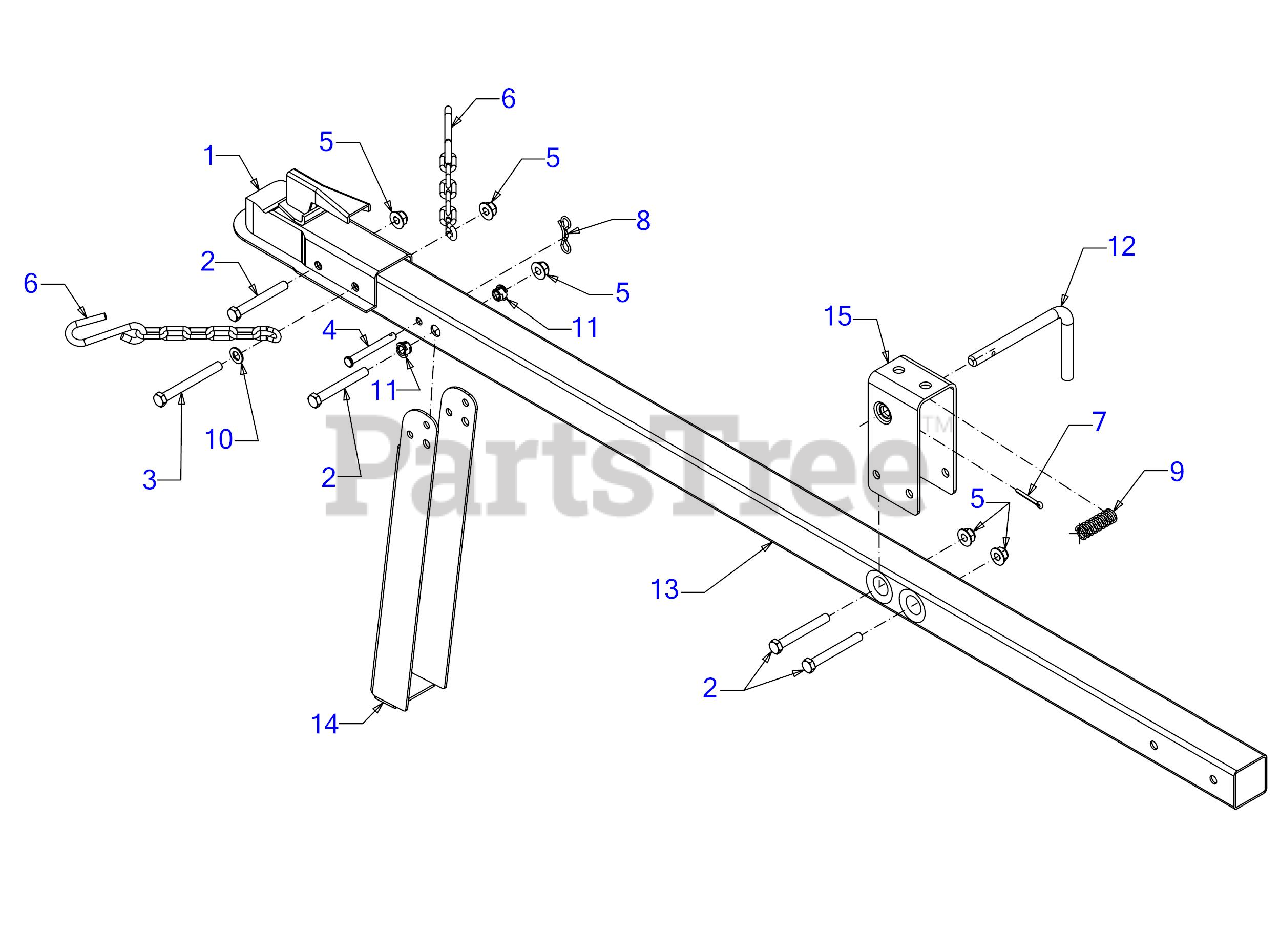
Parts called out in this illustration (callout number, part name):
1	HITCH COUPLING ASSEMBLY
2	SCREW 3/8-16 x 3 GR8
3	SCREW 3/8-16 x 3.50 GR5
4	CLEVIS PIN 5/16 x 2.5
6	LOGSPLITTER TOW CHAIN
7	COTTER PIN-5/32 DIA
8	PIN:COTTER
9	COMPRESSION SPRING
10	FLAT WASHER
11	BUSHING .380 ID
12	LATCH ROD
